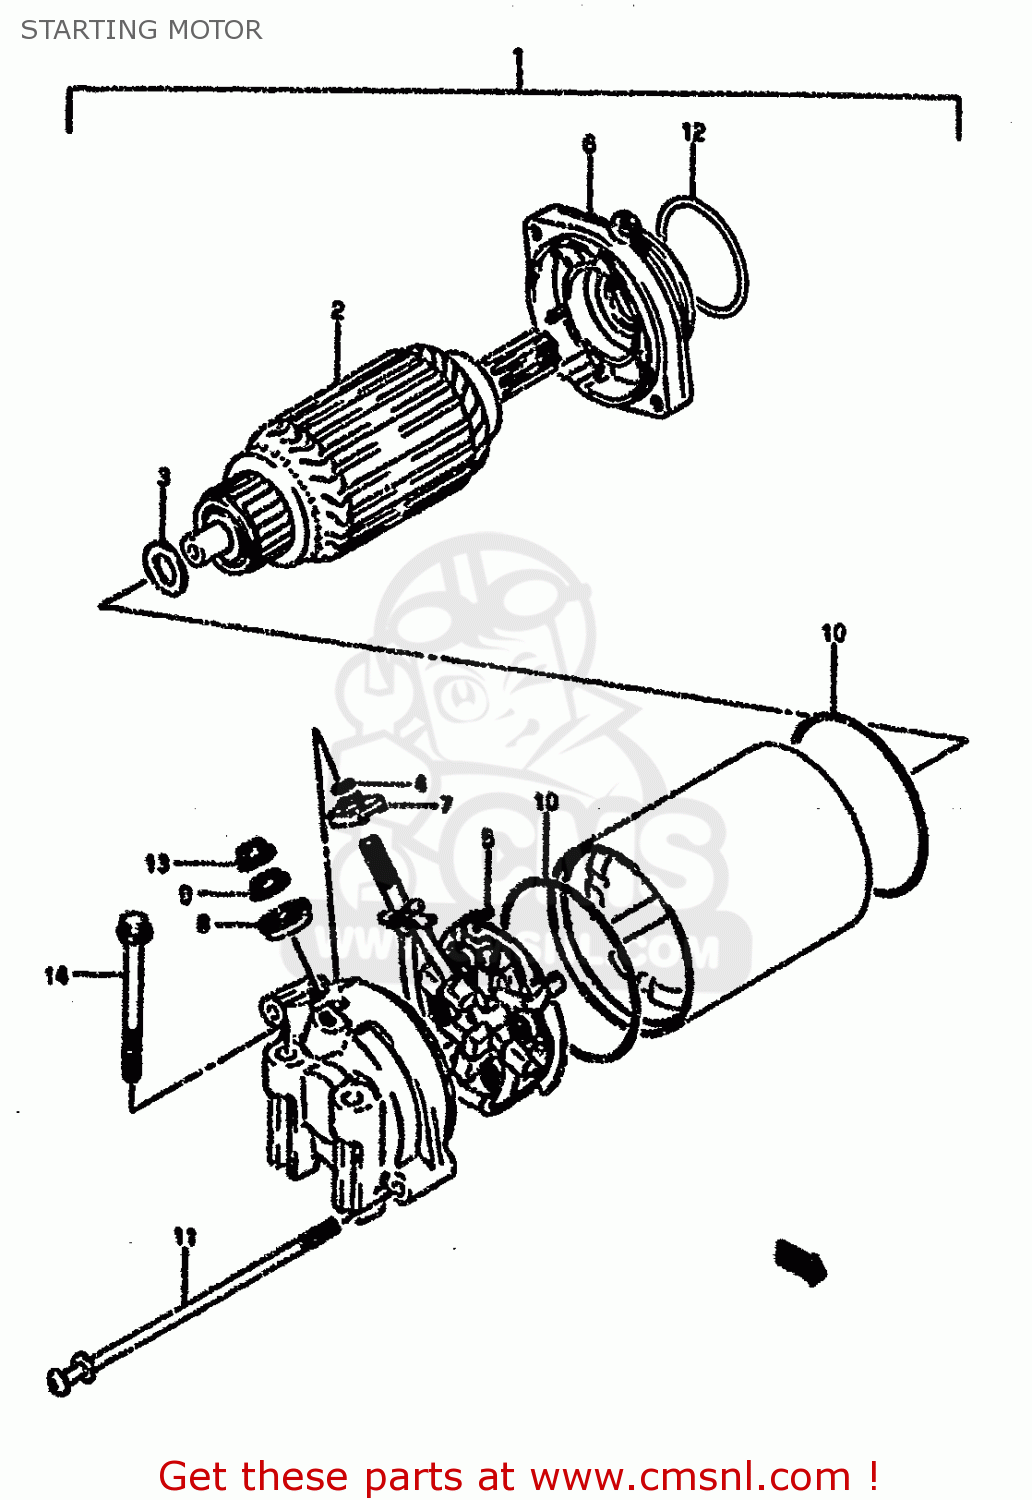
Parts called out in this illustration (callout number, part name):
1	MOTOR ASSY,STARTING
2	ARMATURE
3	SHIM SET,STARTING MOTOR
4	O RING
5	HOLDER SET,BRUSH
6	BRACKET SET
7	BUSHING
8	BUSHING
9	NUT
10	O RING
11	BOLT
12	O RING
13	NUT
14	BOLT
